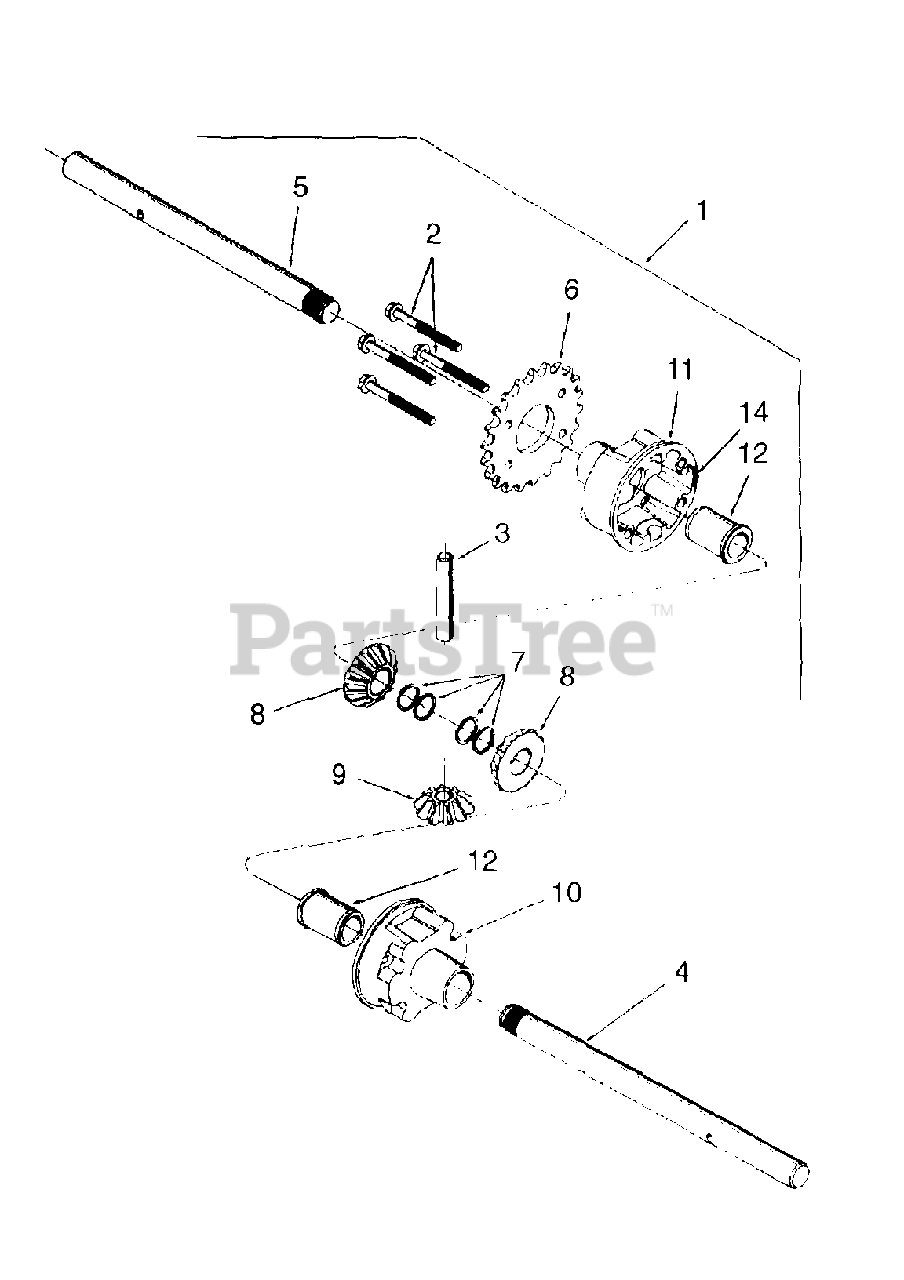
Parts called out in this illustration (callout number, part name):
1	Differential Ass'y Complete
2	Screw, Hex Wash Hd Tapp 1/4-20 x 2-5/16
3	Cross Shaft
4	Axle Shaft, .75 x 10.95
5	Axle Shaft, .75 x 9.82
6	Sprocket, 227
7	Ring, Retaining
8	Gear, Differential, 14T
9	Gear, Differential, 10T
10	Housing, Differential RH
11	Housing, Differential LH
12	Bearing, Flange, .75 ID x 1.0 OD
14	Sealant, Ultra Grey Loctite 5699
